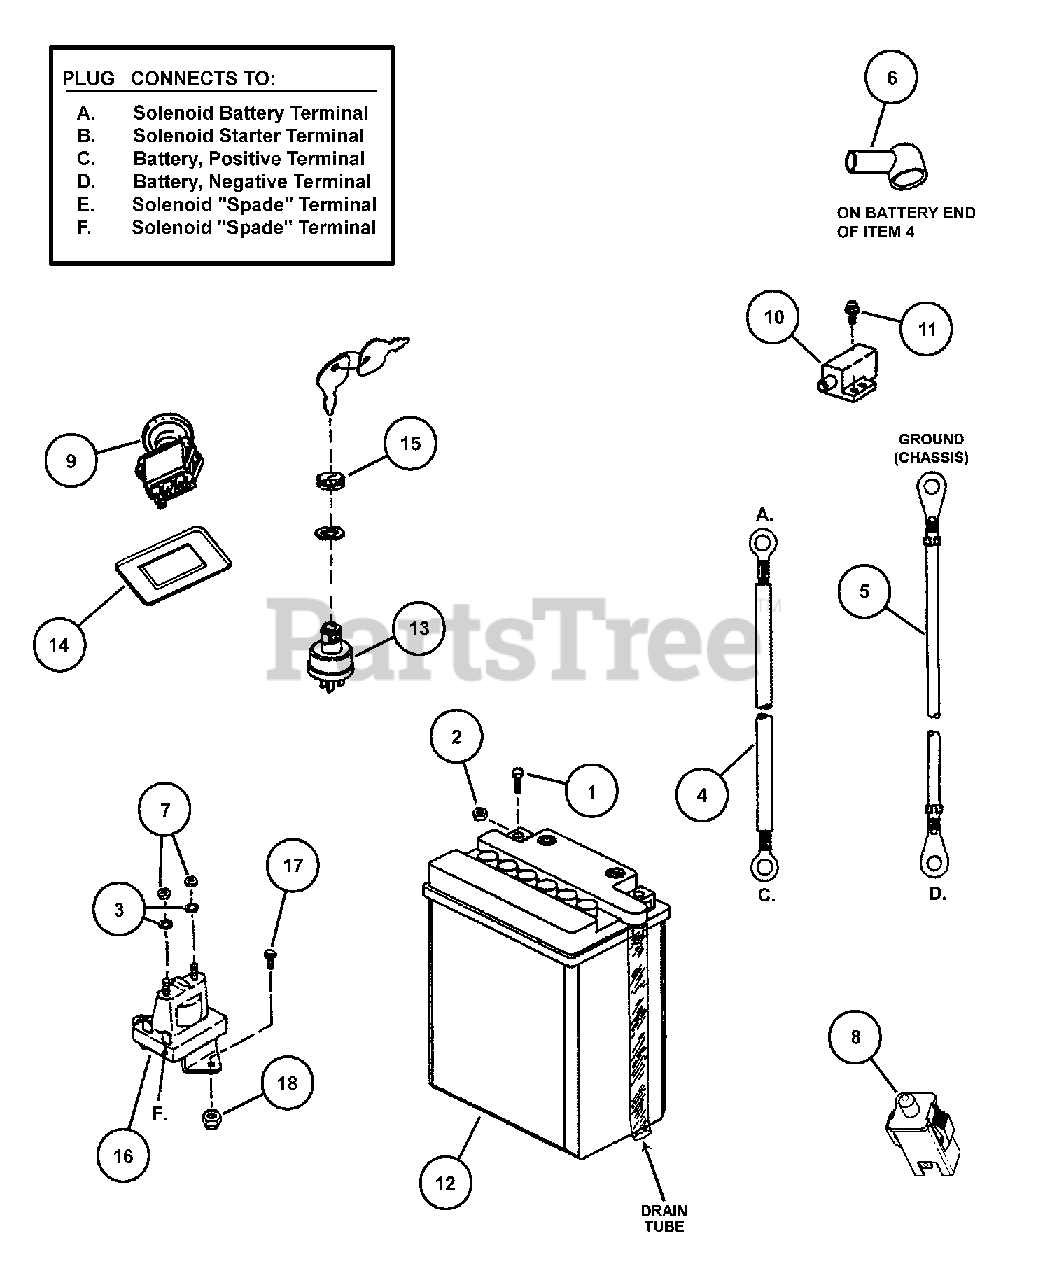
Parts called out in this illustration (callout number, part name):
1	SCREW, #10-24 x 1/2" Hex Head Cap
2	NUT, #10-24 Hex Twin "Whiz" Lock
3	WASHER, 1/4" Internal Tooth Lock
4	WIRE, Positive, 13" long
5	WIRE, Negative, 14" long
6	COVER, Battery Cable
7	NUT, 1/4-20 Hex Jam, GR 5 or B
8	SWITCH, Seat (NO/NC) Snap-In
9	SWITCH, PTO E.C. (Delta Part No. 6201-219)
10	SWITCH, Park Brake (NC/NO)
11	SCREW, #10-24 x 1/2" Hex Washer Self-Tap (Torx)
12	BATTERY, 12V, 3 Amp, 190 Cold Cranking Amp
13	SWITCH, Ignition (After-fire Solenoid)
14	SPACER, PTO Switch
15	BEZEL
16	SOLENOID - Super Trombetta- 2 Terminal
17	SCREW, 1/4-20 x 1/2" Hex Head Cap, GR 5
18	NUT, 1/4-20 Hex Flange Lock
